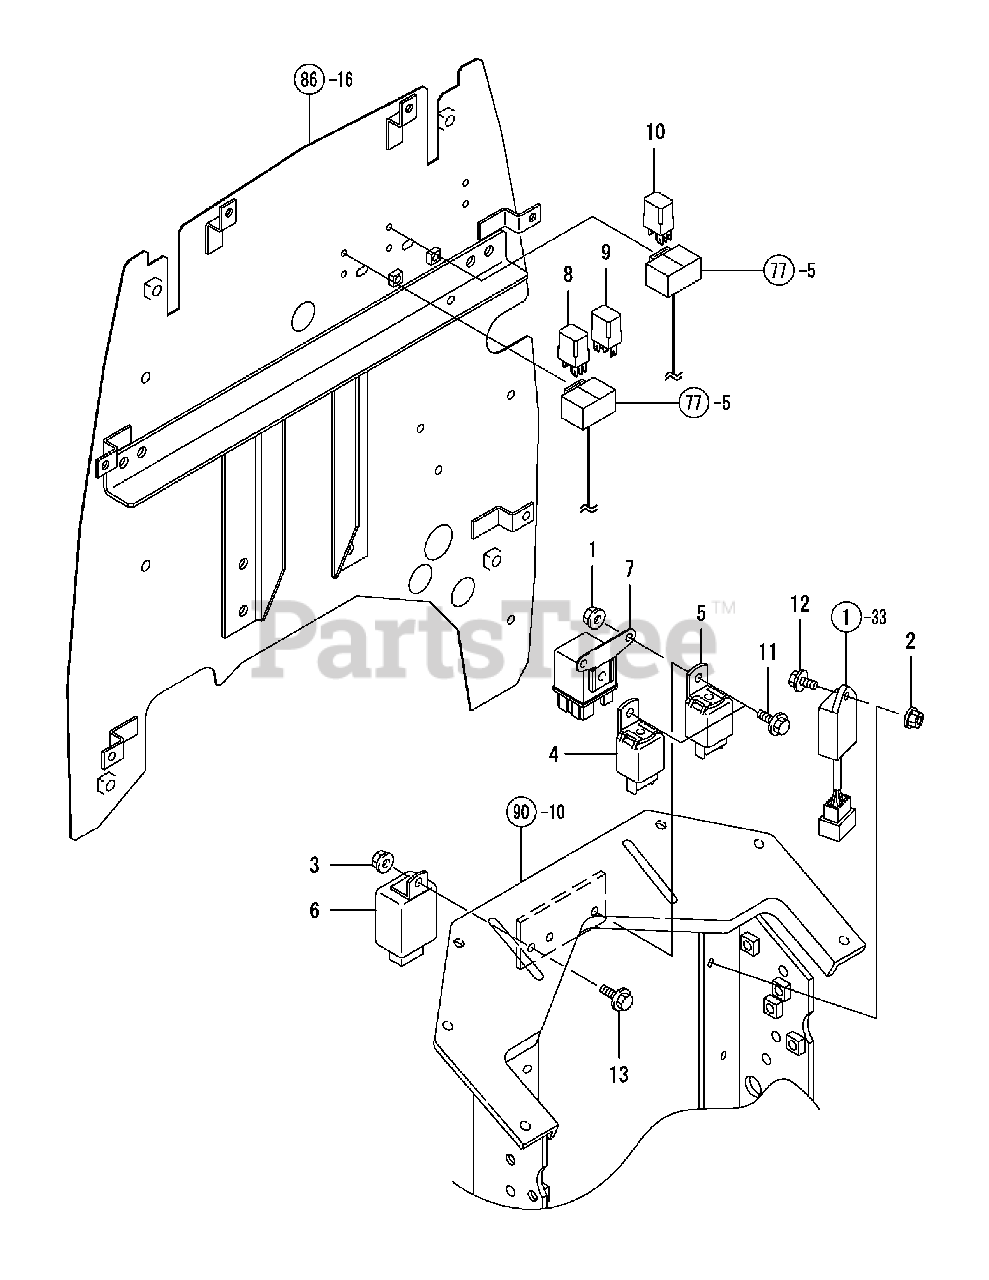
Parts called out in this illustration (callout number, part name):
1	NUT W/WASHER 6
2	NUT W/WASHER 6
3	NUT W/WASHER 6
4	RELAY, STARTER
5	RELAY, STARTER
7	RELAY, GLOW PLUG
8	RELAY, STARTER
9	RELAY, STARTER
10	RELAY, STARTER
11	BOLT M 6X 16 PLATED
12	BOLT M 6X 16 PLATED
13	BOLT M 6X 16 PLATED
